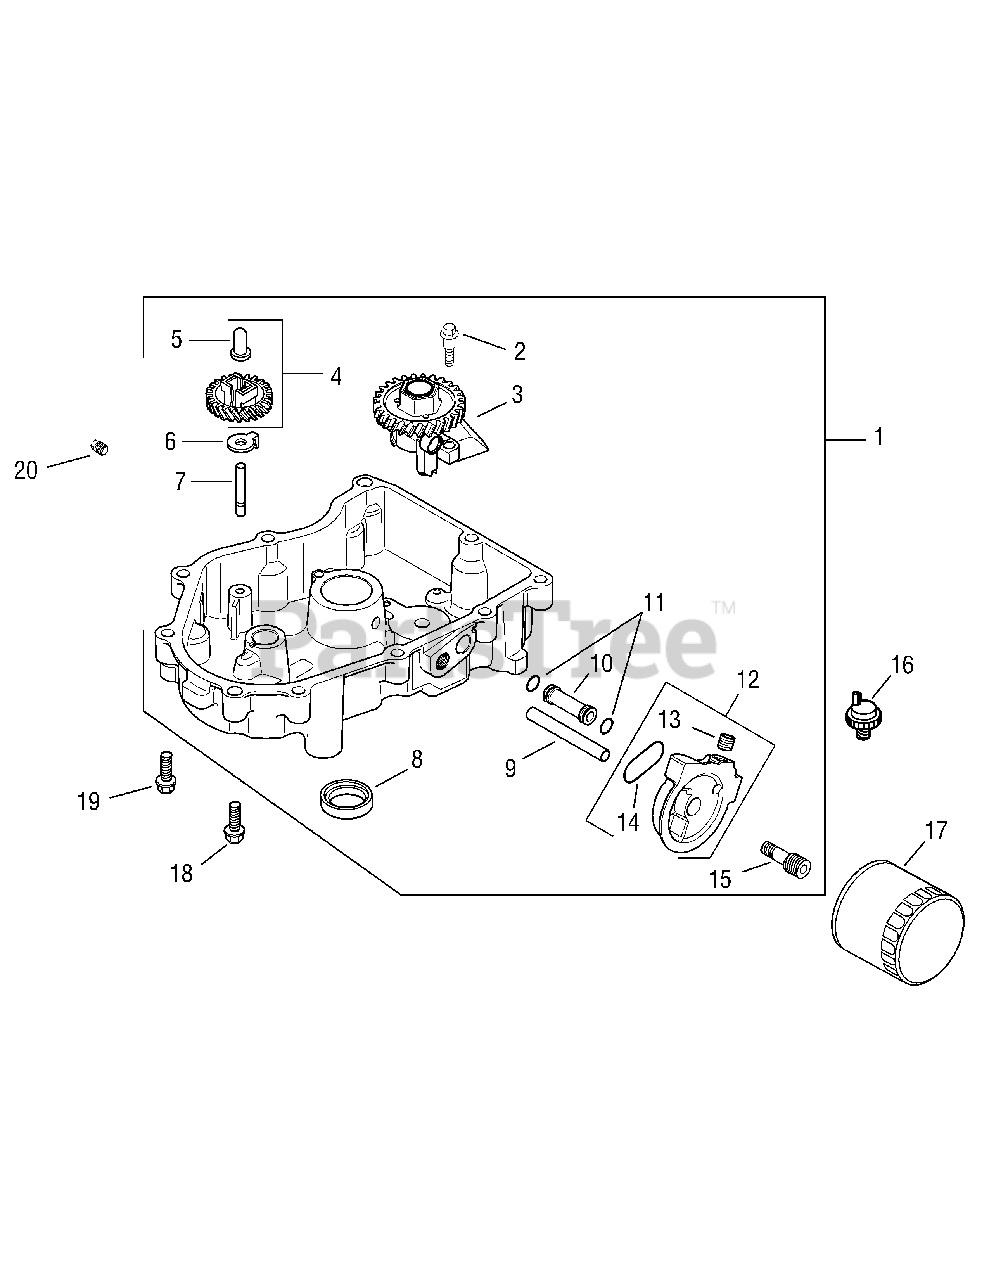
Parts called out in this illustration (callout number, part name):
1	Pan assembly, oil (Includes 2-15)
2	Screw, hex. flange thread forming shoulder
3	Oil pump assembly
4	Kit, governor gear w/pin (Includes 5)
5	Pin, governor regulating
7	Shaft, governor gear
8	Seal, oil (PTO end)
9	Tube, oil feed - filter to oil pan
10	Tube, oil feed - oil pan to filter
12	Adapter, oil filter (Includes 13,14)
13	Plug, hex. ctsk. 1/8"
14	O-Ring, oil filter adapter
15	Nipple, oil filter
16	Switch, pressure
17	Filter, oil
18	Screw, hex. flange M8x1.25x45
19	Screw, hex. flange M8x1.25x45
20	Plug, sq. hd. solid 3/8"
